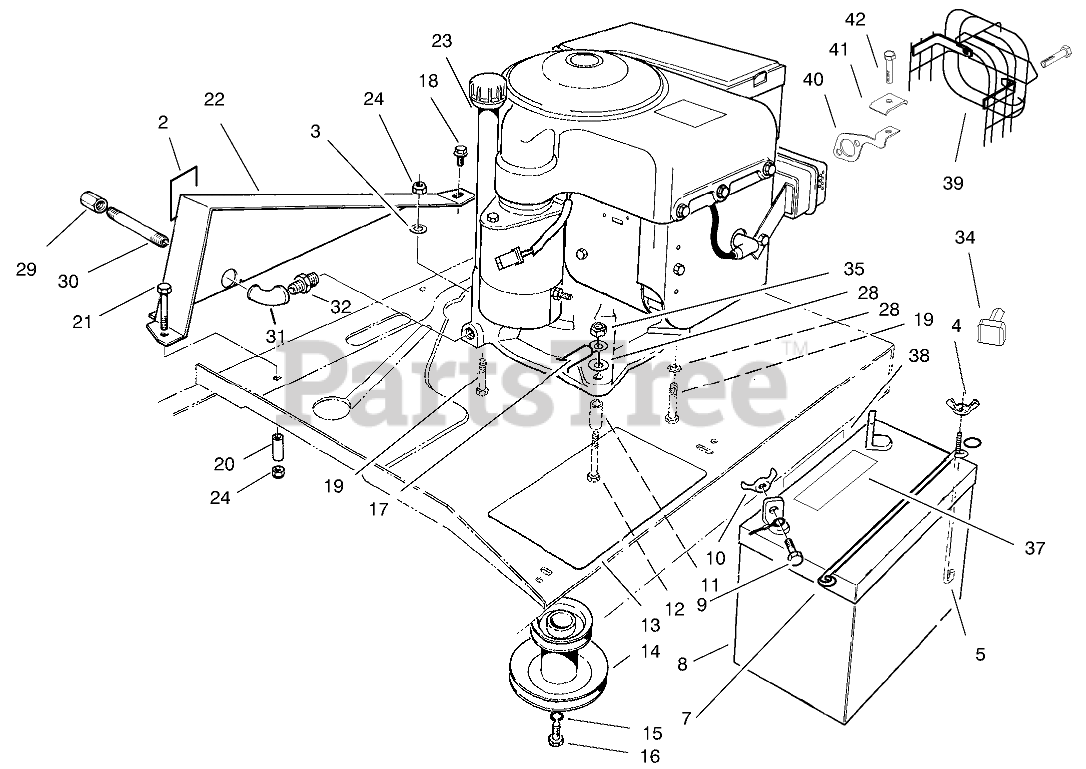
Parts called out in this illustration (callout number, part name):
2	DECAL-EUROPE
3	WASHER-PLAIN
4	NUT-WING
5	POST-BATTERY
7	ROD-BATTERY HOLD DWN
8	BATTERY-155 CCA
9	SCREW-HH
10	NUT-WING
11	SPACER-PIVOT
12	SCREW-HH
13	PAD-SKID, ANTI
14	PULLEY - ENGINE
15	WASHER-FLAT
16	SCREW-HH
17	WIRE ASM
18	SCREW-HWHTF
19	SCREW-HH
20	GUIDE-BELT
21	SCREW-HH
22	GUIDE-CHAIN
23	Engine-8 H.P. B & S
24	NUT-LOCK, NI
28	WASHER-LOCK
29	CAP-PIPE
30	NIPPLE-PIPE
31	ELBOW-STREET
32	BUSHING-PIPE
34	BOOT-TERMINAL
35	NUT-HEX, SIDE DEFORM
37	Decal-Battery
38	Decal-Battery
39	GUARD - MUFFLER
40	BRACKET - MUFFLER GUARD
41	TAB - MUFFLER GUARD
42	SCREW-HWHTF
